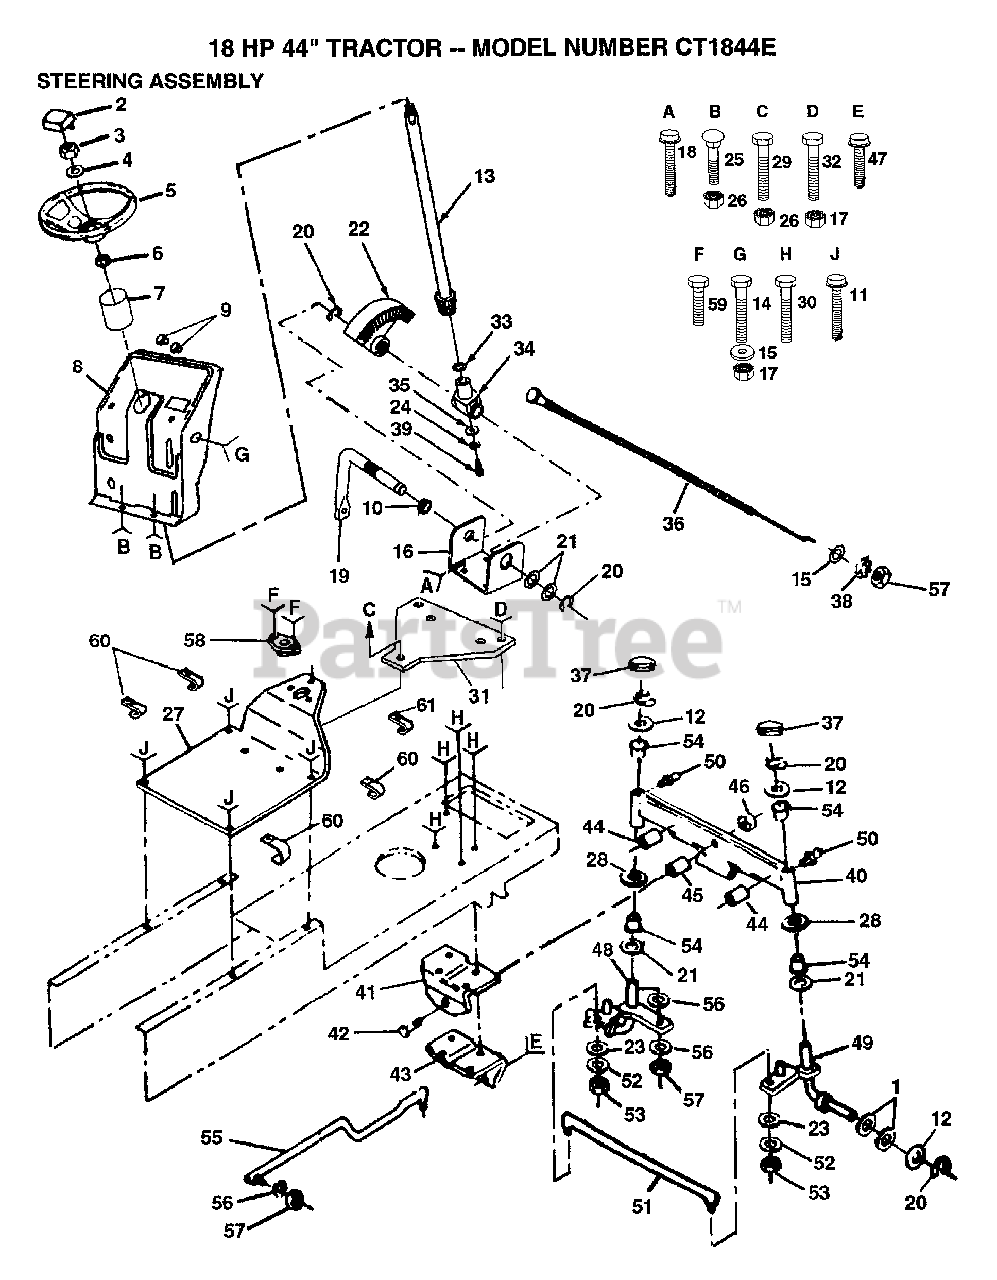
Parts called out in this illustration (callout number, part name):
1	WASHER
2	ST WHL INSERT CAP
4	WASHER
6	ADAPTER LT
7	SLEEVE LTV
9	PLUG-DASH T
10	NYLINER T
11	SCREW LT
12	WASHER
13	SHAFT&GEAR STR T
15	WASHER
16	"BRKT,STEERING"
17	NUT
18	SCREW
20	RING
21	WASHER .T
22	GEAR SECTOR
23	WASHER M
24	LOCKWASHER
25	SCREW
28	WASHER
30	SCREW SPECIAL
32	BOLT
33	THRUST WASHER
34	SUPPORT.SHAFT
36	CHOKE CONTROL
37	CAP
38	LOCKWASHER
39	"SCREW,SPECIAL"
40	FRONT AXLE
41	SUPPORT-SADDL T
42	BOLT LT
43	SUPPORT.SADDLE.FT
44	AXLE PIN
45	BEARING
46	"NUT-LOC,FLANGE LT"
47	SCREW LT
48	SPINDLE LH
49	SPINDLE RH
50	ZERK M
51	TIE ROD
52	LOCKWASHER
53	NUT.LOCK.5/16-24
54	COL. SRTG. BEAR.
56	LOCKWASHER
60	CLIP T
61	INSUL CLIP T
